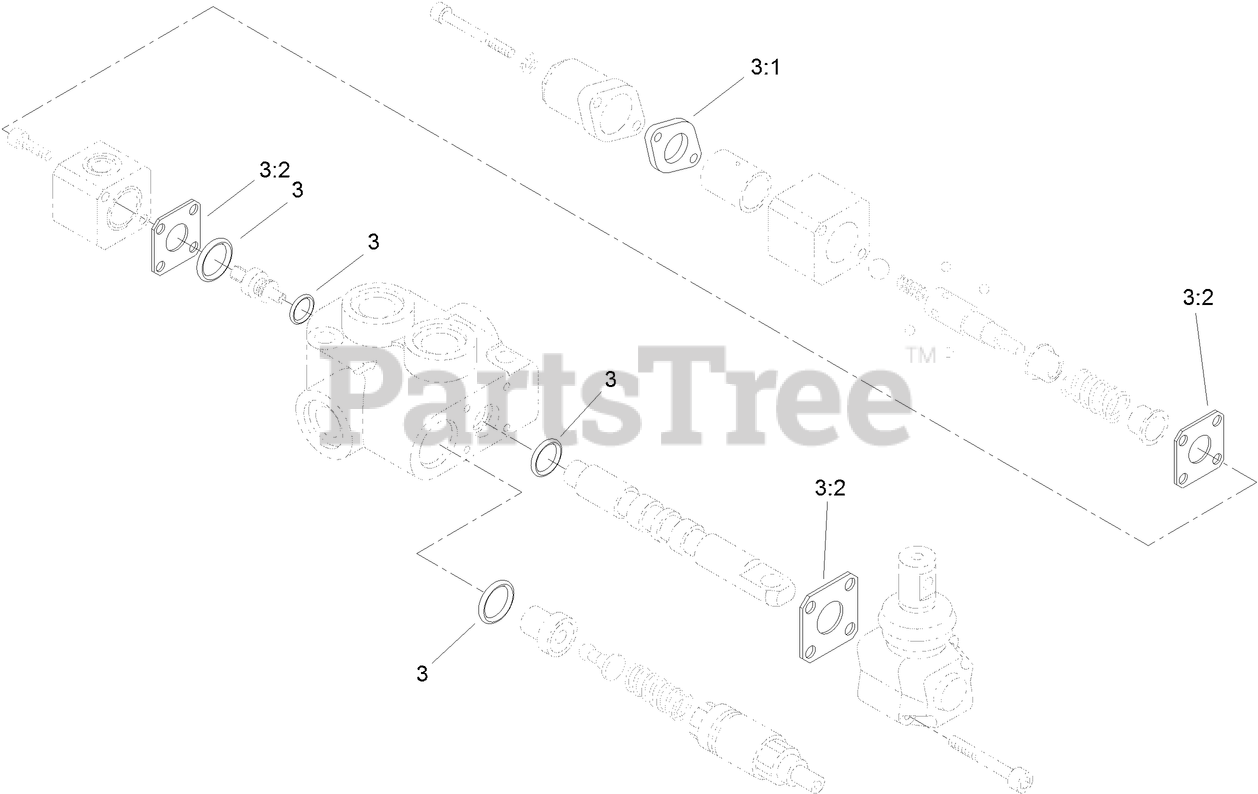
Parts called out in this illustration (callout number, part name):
3	SEAL KIT
3:1	GASKET
3:2	GASKET
